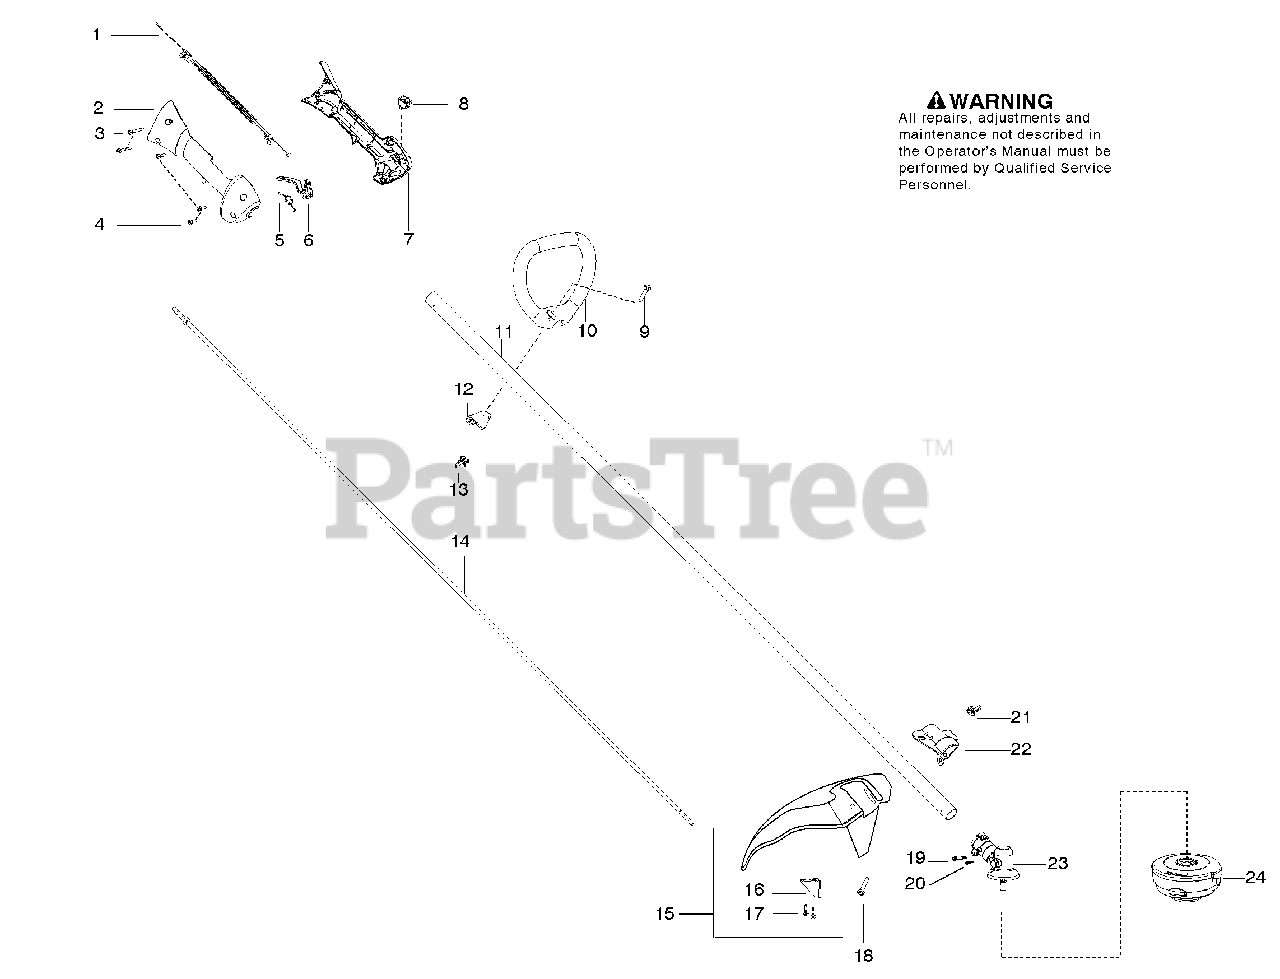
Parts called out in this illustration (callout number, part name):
1	AssyCable/Wire Harness
2	HousingThrottle
5	SpringTrigger
7	HousingThrottle
8	Switch
10	HandleAssist
11	KitDriveshaft
12	ClampHandle
13	Wingnut
15	KitShield
16	LimiterLine
21	Wingnut
22	BracketShield
23	Gearbox 1"
24	AssyT25 Cutting Head
